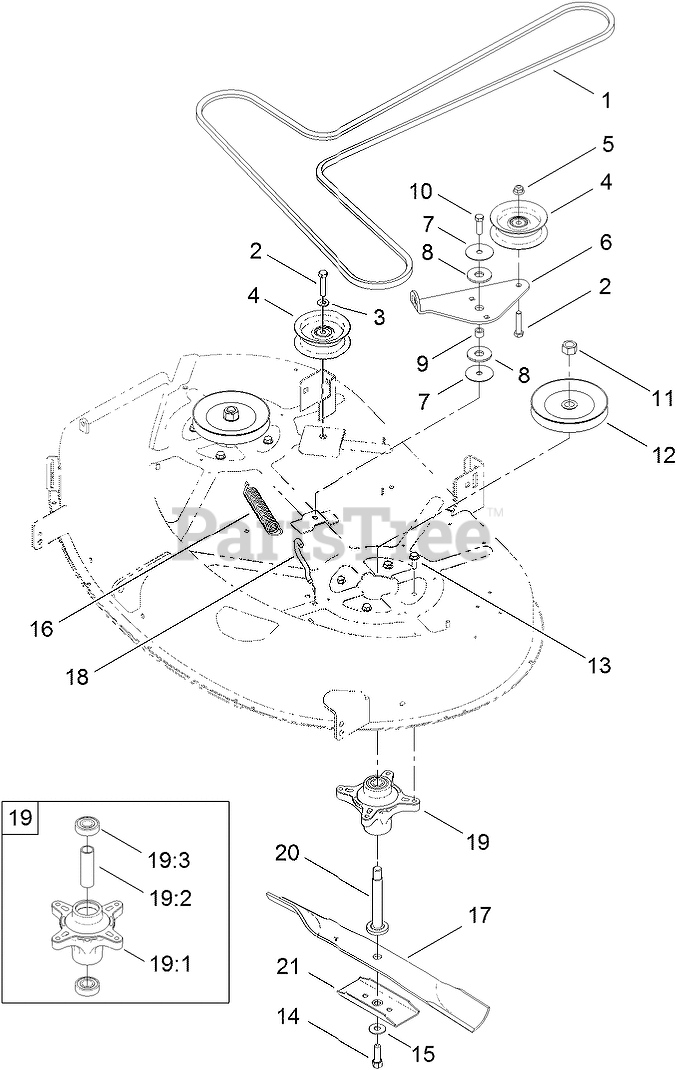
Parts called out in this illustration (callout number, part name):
1	V-BELT
2	SCREW-HH
3	WASHER-FLAT
4	PULLEY-IDLER, FLAT
5	NUT-HF, NI
6	ARM-IDLER
7	WASHER
8	WASHER-FRICTION, COMPOSITE
9	SPACER
10	SCREW-HH
11	NUT-HEX
12	PULLEY
13	SCREW-TAPTITE
14	SCREW-HH
15	WASHER-BELLEVILLE
16	SPRING-EXTENSION
17	BLADE-21.6 INCH
18	HOOK-RETURN, SPRING
19	SPINDLE ASM
19:1	SPINDLE
19:2	SPACER
19:3	BEARING-BALL
20	SHAFT-SPINDLE
21	STIFFENER-BLADE
